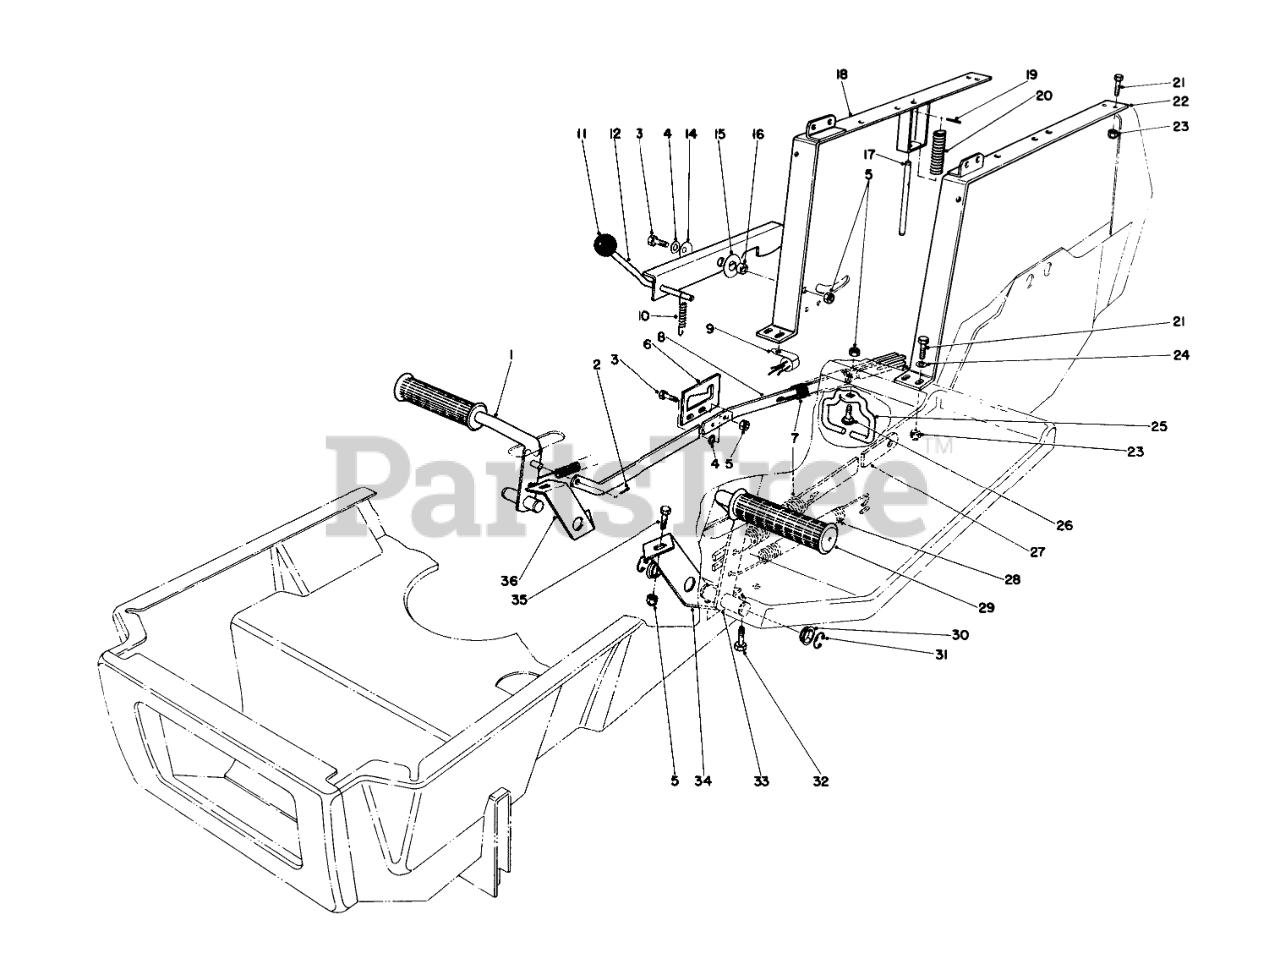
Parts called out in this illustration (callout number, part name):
1	BRAKE PEDAL WA BO
2	PIN-COTTER
3	SCREW-HH
4	WASHER-PLAIN
5	NUT-LOCK, CONE
6	LATCH PLT-BRAKE ROD
7	EXT SPRING O
8	LINK BRAKE ROD WAB
9	Module Interlock
10	CONT ROD SPRING 0
12	PARKING BRAKE WA B
14	WASHER-BELLEVILLE
15	WASHER-PLASTIC
16	SPACER
17	Pin-Seat Switch
18	Strap-Rear Body R. H.
19	PIN-ROLL, SLOTTED
20	DECK IDLER SPRING
21	SCREW-HH
22	Strap-Rear Body L.H.
23	NUT-LOCK, CONE
24	WASHER-FLAT
25	Belt Guide
26	Bolt
27	CLUTCH ROD LINK B
28	SPRING-EXTENSION
29	FOOT PAD
30	Nyliner
31	E-RING
32	SCREW-HWHTF
33	CLUTCH PEDAL WA BO
34	LH PEDAL SUPT B
35	SCREW-HH
36	RH PEDAL SUPT B
